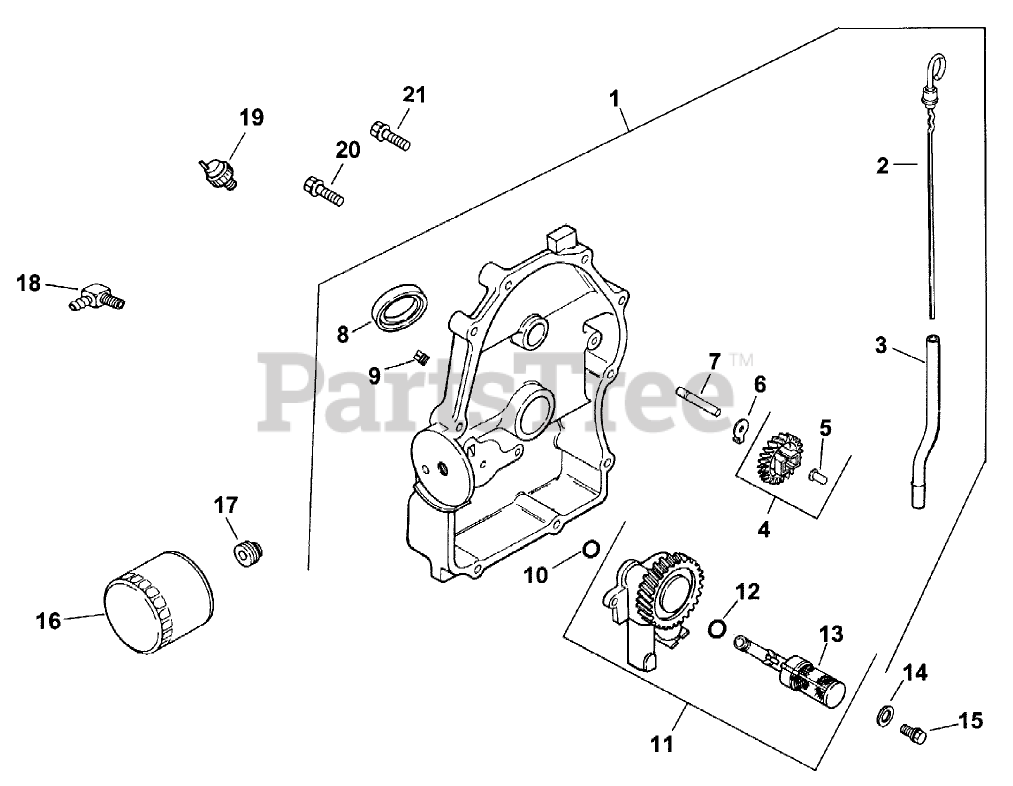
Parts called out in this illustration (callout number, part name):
1	Plate, closure assembly (Includes 2-12)
2	Dipstick
3	Tube-Dipstick
4	Kit, governor gear (Includes 5)
5	PIN-REGULATING, GOVERNOR
6	Tab-Locking
7	SHAFT-GEAR, GOVERNOR
8	SEAL-OIL (P-T-O END)
9	Plug
10	O-Ring
11	Oil pump assembly (Includes 12,13)
12	O-RING
13	TUBE-PICK UP, OIL
14	WASHER-FLAT (6 MM)
15	SCREW-FLANGE, THREAD FORMING (M6X1.0X25)
16	Filter-Oil
17	Nipple-Filter, Oil
18	Connector-Hose, 90 Deg
19	SWITCH-PRESSURE, OIL
20	Screw-HF (M8x1.25x45)
21	SCREW-FLANGE (M8X1.25X45)
